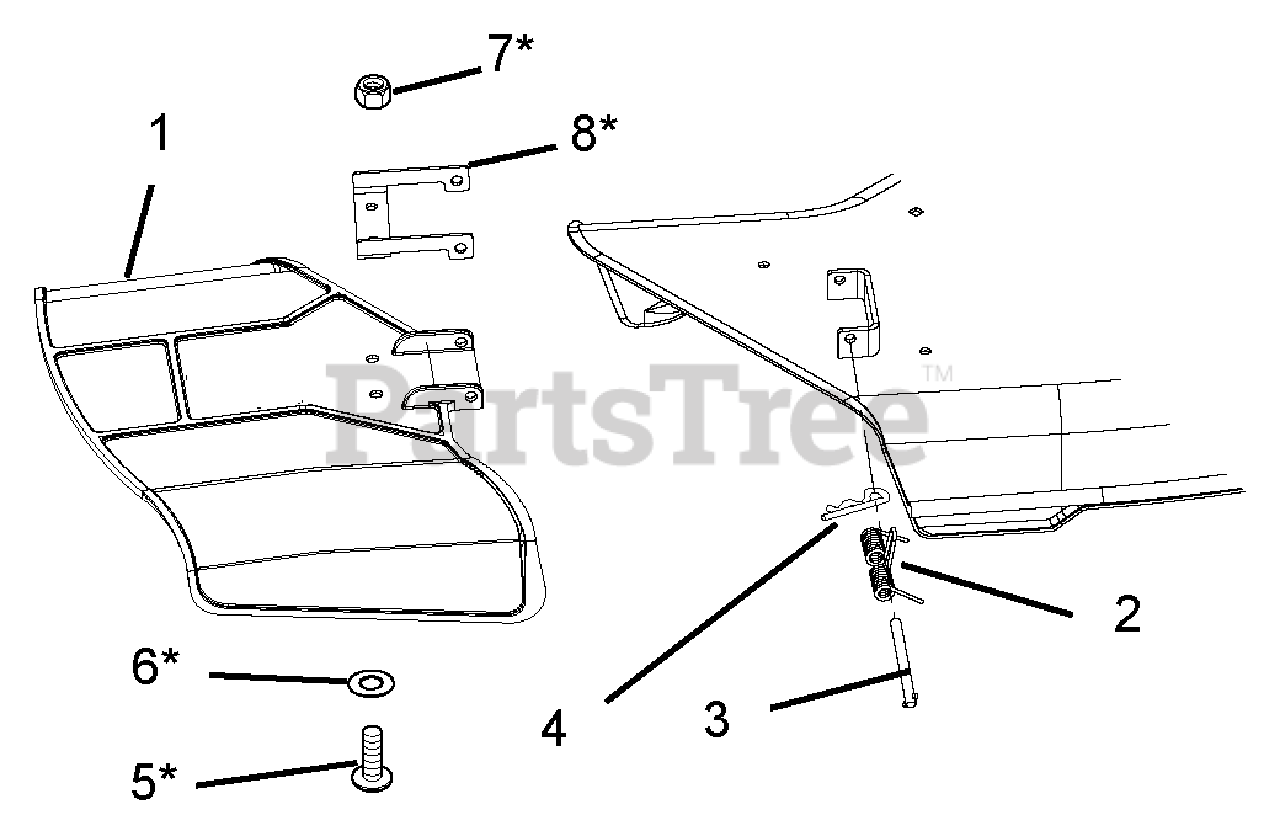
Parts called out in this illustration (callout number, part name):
1	MOLDED CHUTE, ZOOM
2	SPRING, TORSION
3	PIN, 5/16 X 3.88"
4	PIN-HAIR INT .08X.18X1.18 YWZC
5	SCR-SKH .31-18X.75 BTNHD YWZC
6	@WSHR-FL-STL.38X.875X.083 YWZC
7	@NUT-LK-TOP-FLG .31-18 YWZC
8	CHUTE REINFORCEMENT
